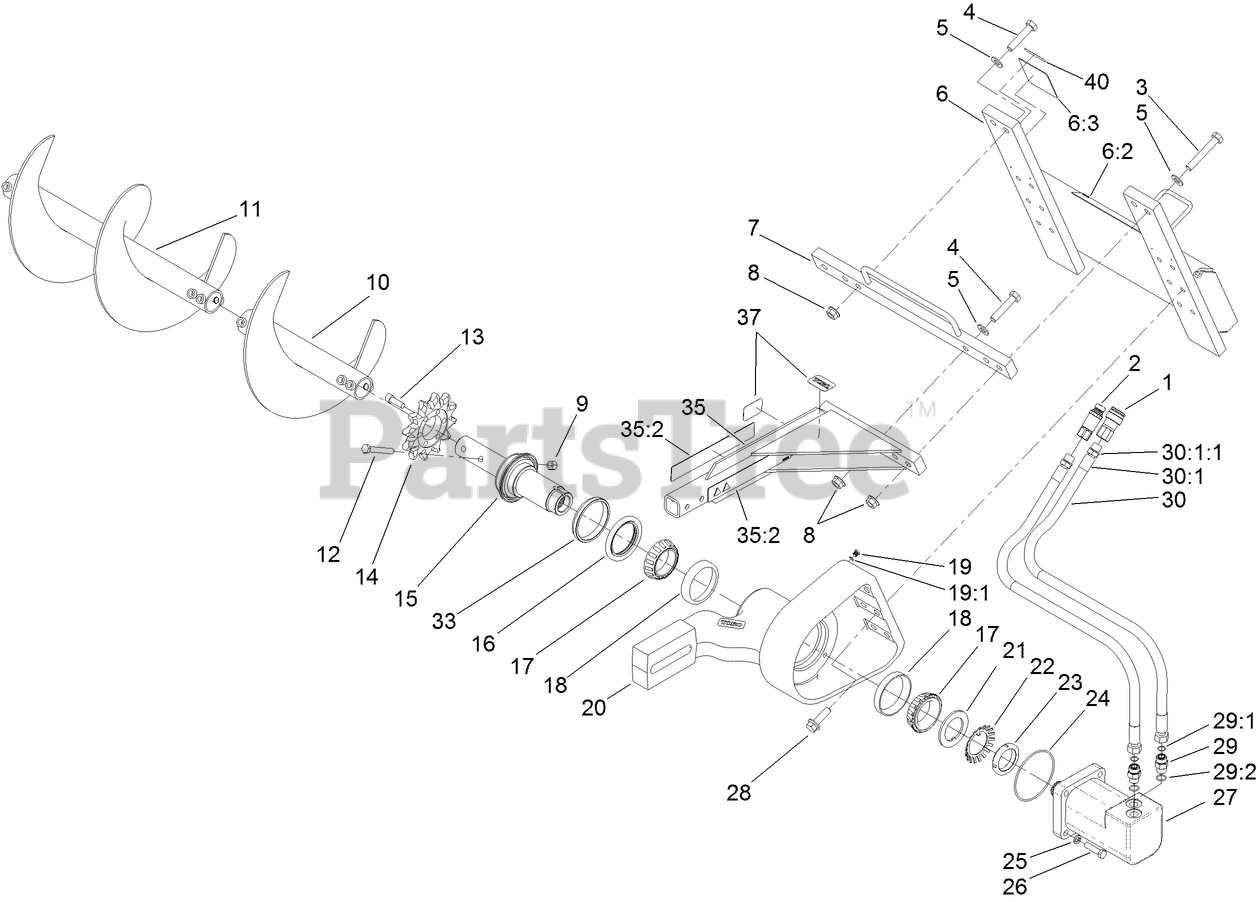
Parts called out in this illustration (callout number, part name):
1	COUPLER-FACE, FLUSH
2	NIPPLE-CONNECT, PRESSURE
3	SCREW-HH
4	SCREW-HH
5	WASHER-FLAT
6	MOUNT ASM
6:2	DECAL-DANGER
6:3	DECAL-DANGER
7	CROSSBAR ASM
8	NUT-FLANGE
9	NUT-LOCK, NI
10	AUGER ASM
11	AUGER ASM
12	SCREW-HH
13	SCREW-HSH
14	SPROCKET-TRENCHER
15	SHAFT-TRENCHER
16	SEAL-SHAFT
17	CONE-BEARING
18	CUP-BEARING
19	PLUG ASM
19:1	O-RING
20	MOUNT-BOOM
21	WASHER-TONGUED
22	WASHER-LOCK, BEARING
23	NUT-LOCK, BEARING
24	O-RING
25	WASHER-LOCK
26	SCREW-HH
27	MOTOR-HYD, HIGH SPEED
29	FITTING-STRAIGHT
29:1	O-RING
29:2	O-RING
30	HOSE ASM
30:1	FITTING-STRAIGHT
30:1:1	O-RING
33	SPACER
35	SAFETY RAIL ASM
35:2	DECAL-DANGER
37	DECAL
40	DECAL-WARNING
